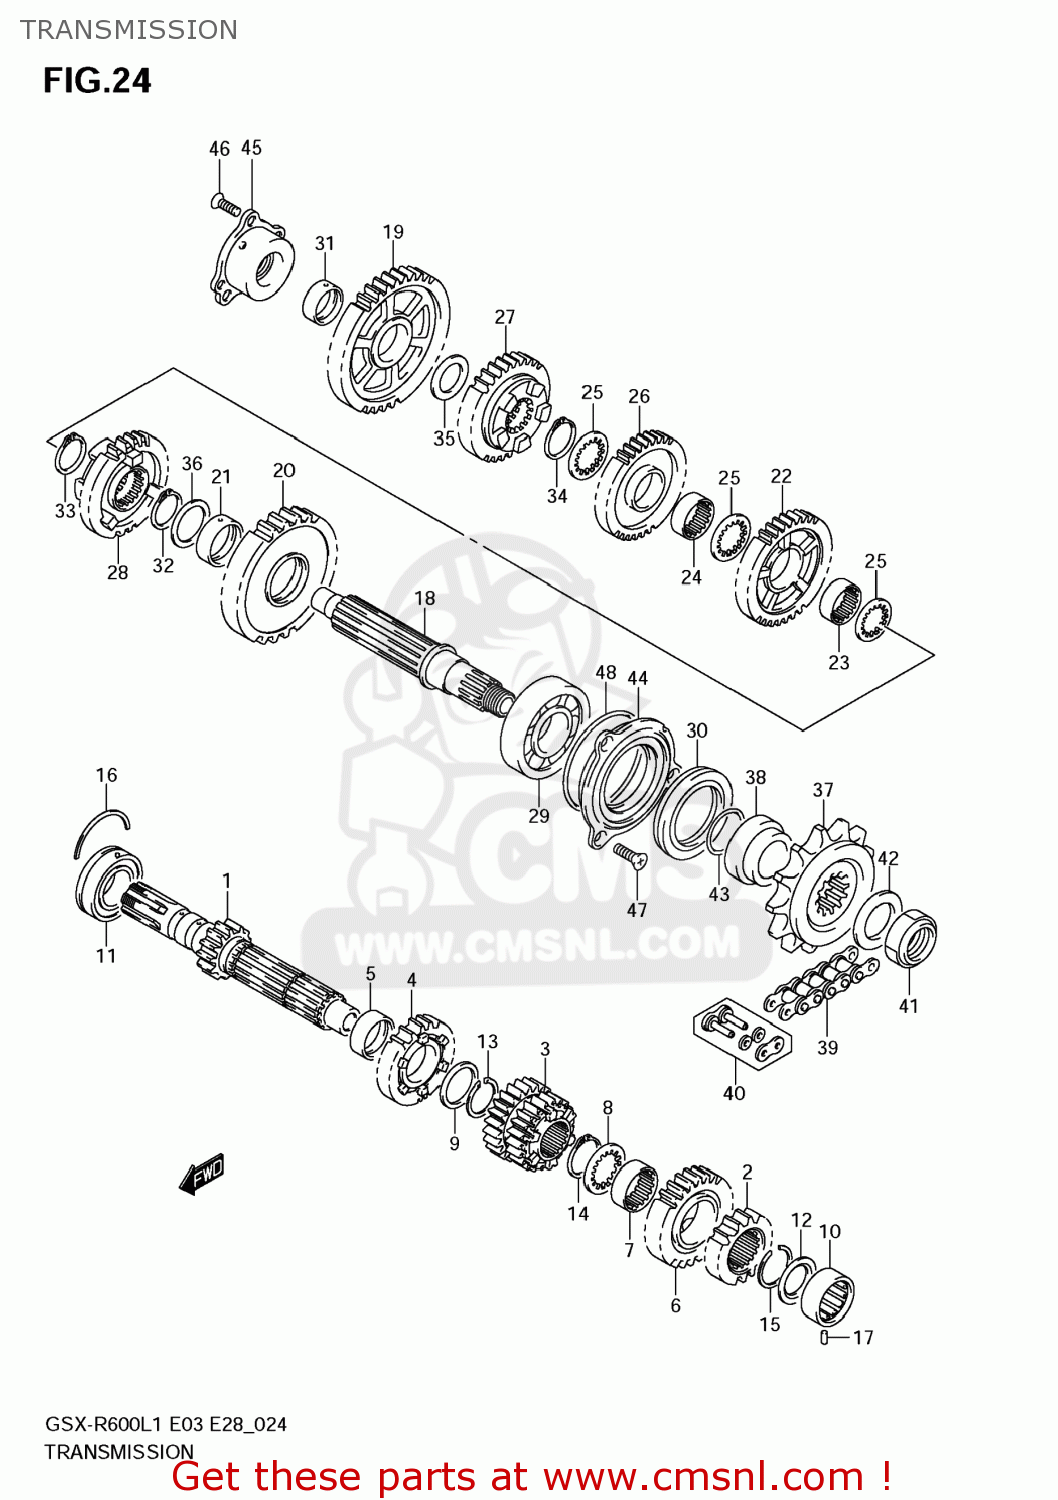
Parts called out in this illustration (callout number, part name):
1	SHAFT,COUNTER
2	GEAR,2ND DRIVE
3	GEAR,3RD & 4TH DRIVE
4	GEAR,5TH DRIVE
5	BUSH,5TH DRIVE GEAR
6	GEAR,6TH DRIVE
7	BUSH,6TH DRIVE GEAR
8	WASHER,LOCK
9	WASHER(27X36X1)
10	BEARING(20X34X13.5)
11	BEARING(25X62X17)
12	SEAL,OIL(20X31.2X2.7)
13	CIRCLIP
14	CIRCLIP
15	CIRCLIP
16	C RING
17	PIN(6X10)
18	SHAFT,DRIVE
19	GEAR,1ST DRIVEN
20	GEAR,2ND DRIVEN
21	BUSH,2ND DRIVEN GEAR
22	GEAR,3RD DRIVEN
23	BUSH,3RD DRIVEN GEAR
24	BUSH,3RD DRIVEN GEAR
25	WASHER,3RD & 4TH DRIVEN
26	GEAR,4TH DRIVEN
27	GEAR,5TH DRIVEN(NT:31)
28	GEAR,6TH DRIVEN
29	BEARING(28X68X18)
30	SEAL,OIL(42X62X7)
31	BUSH(22X26X9)
32	CIRCLIP
33	CIRCLIP
34	CIRCLIP
35	SHIM(22X34X1)
36	WASHER(27X36X1)
37	SPROCKET,ENGINE(16T)
38	SPACER,ENGINE SPROCKET
39	CHAIN,DRIVE
40	JOINT SET,DRIVE CHAIN
41	NUT
42	WASHER(25X41X3)
43	O RING(D:2.4,ID:23.7)
44	RETAINER,DRIVE SHAFT BEARING,L
45	HOUSING,DRIVE SHAFT SET
46	SCREW(6X20)
47	SCREW(6X20)
48	O RING(D:1.8,ID:67.5)
